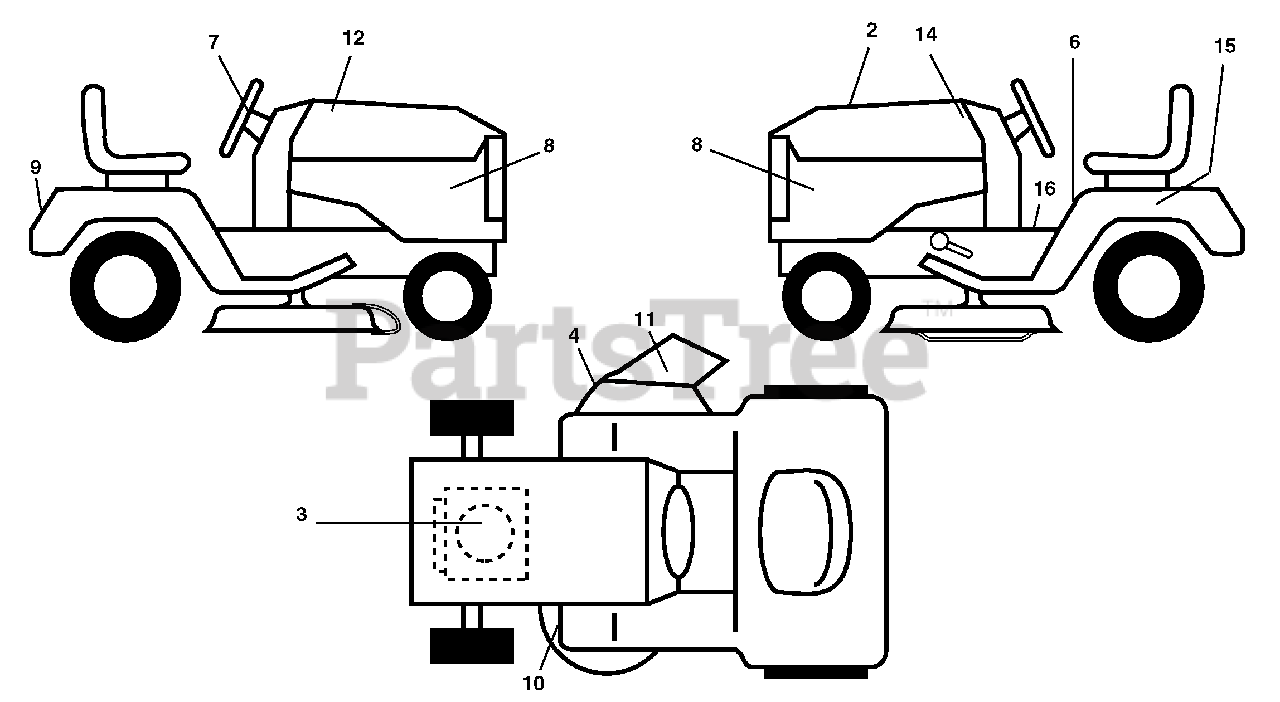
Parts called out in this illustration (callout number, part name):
2	Decal, Replacement
3	Decal, Engine HP
4	Decal Warning
6	Decal, Fender Danger English
7	Decal Ins Str Wh
8	Decal, Side Panel
9	Decal, Fender
10	Decal, V-Belt Sch.
12	Decal, Hood RH
14	Decal, Hood LH
15	Decal, Caution, Battery
16	Decal, Oper
16	Decal Bypass
16	Decal, Handle Lft Height Adj.
16	Manual, Operator's (E&F)
16	Manual, Parts (E&F)
